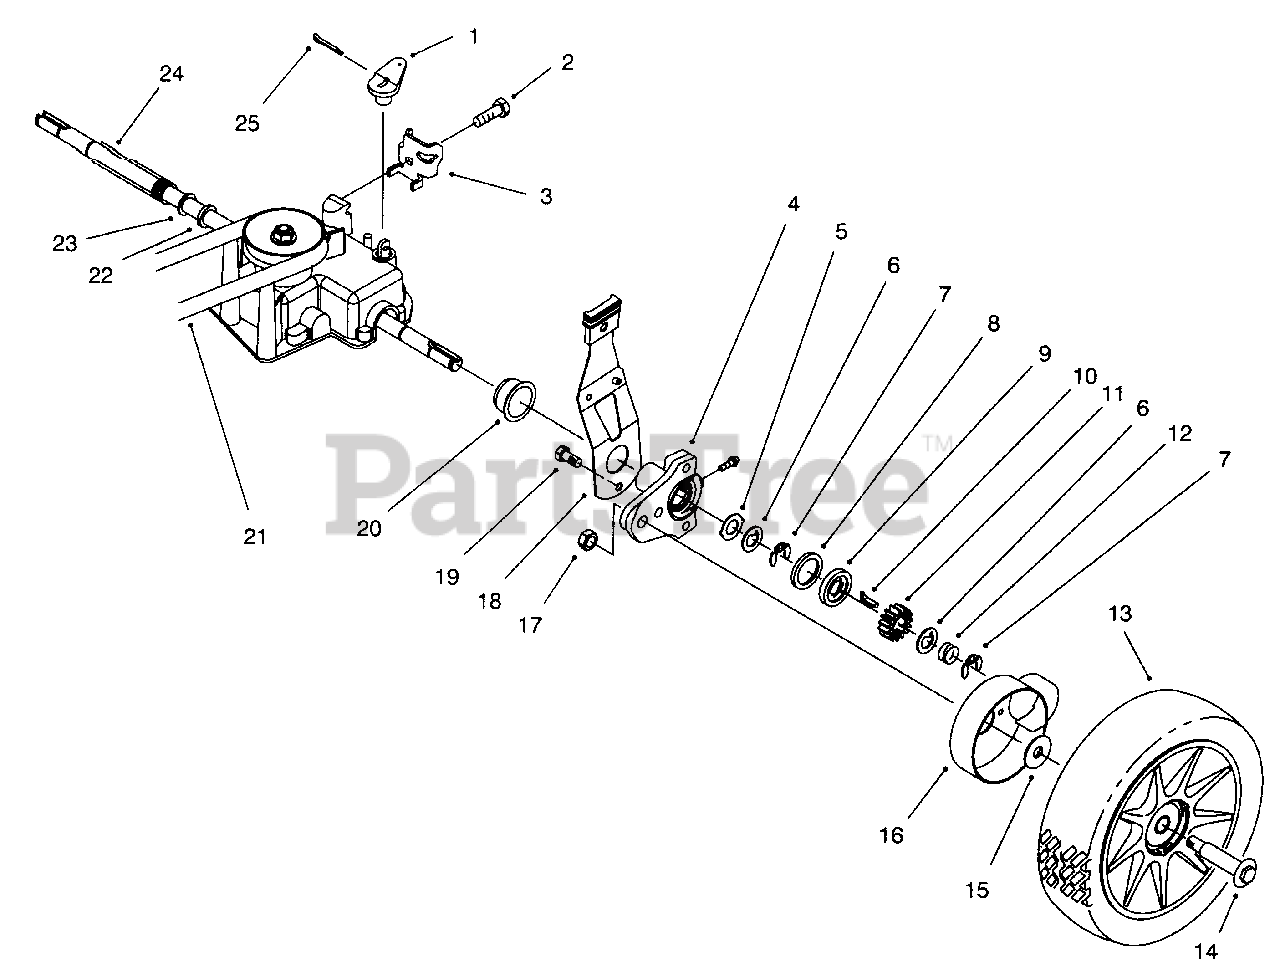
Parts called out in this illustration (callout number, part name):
1	Lever Shift
2	Screw-Tapping
3	Retainer-Cable
4	Arm-Rear Height Adjust.
5	Washer-Thrust
6	Washer-Thrust Keyed
7	Ring-Retaining
8	Ring-Friction
10	Key-Rocking L.H.
11	Gear-Pinion
12	Spring-Compression
13	Wheel & Tire Assembly
14	Bolt-Shoulder
15	Washer-Stepped
16	Cover-Wheel
17	Nut-Lock
18	Spring Arm Assembly-L.H.
19	Screw-Hex Hd Tapping
22	Washer-Flat
24	Cover-Drive Shaft
25	Pin-Cotter
